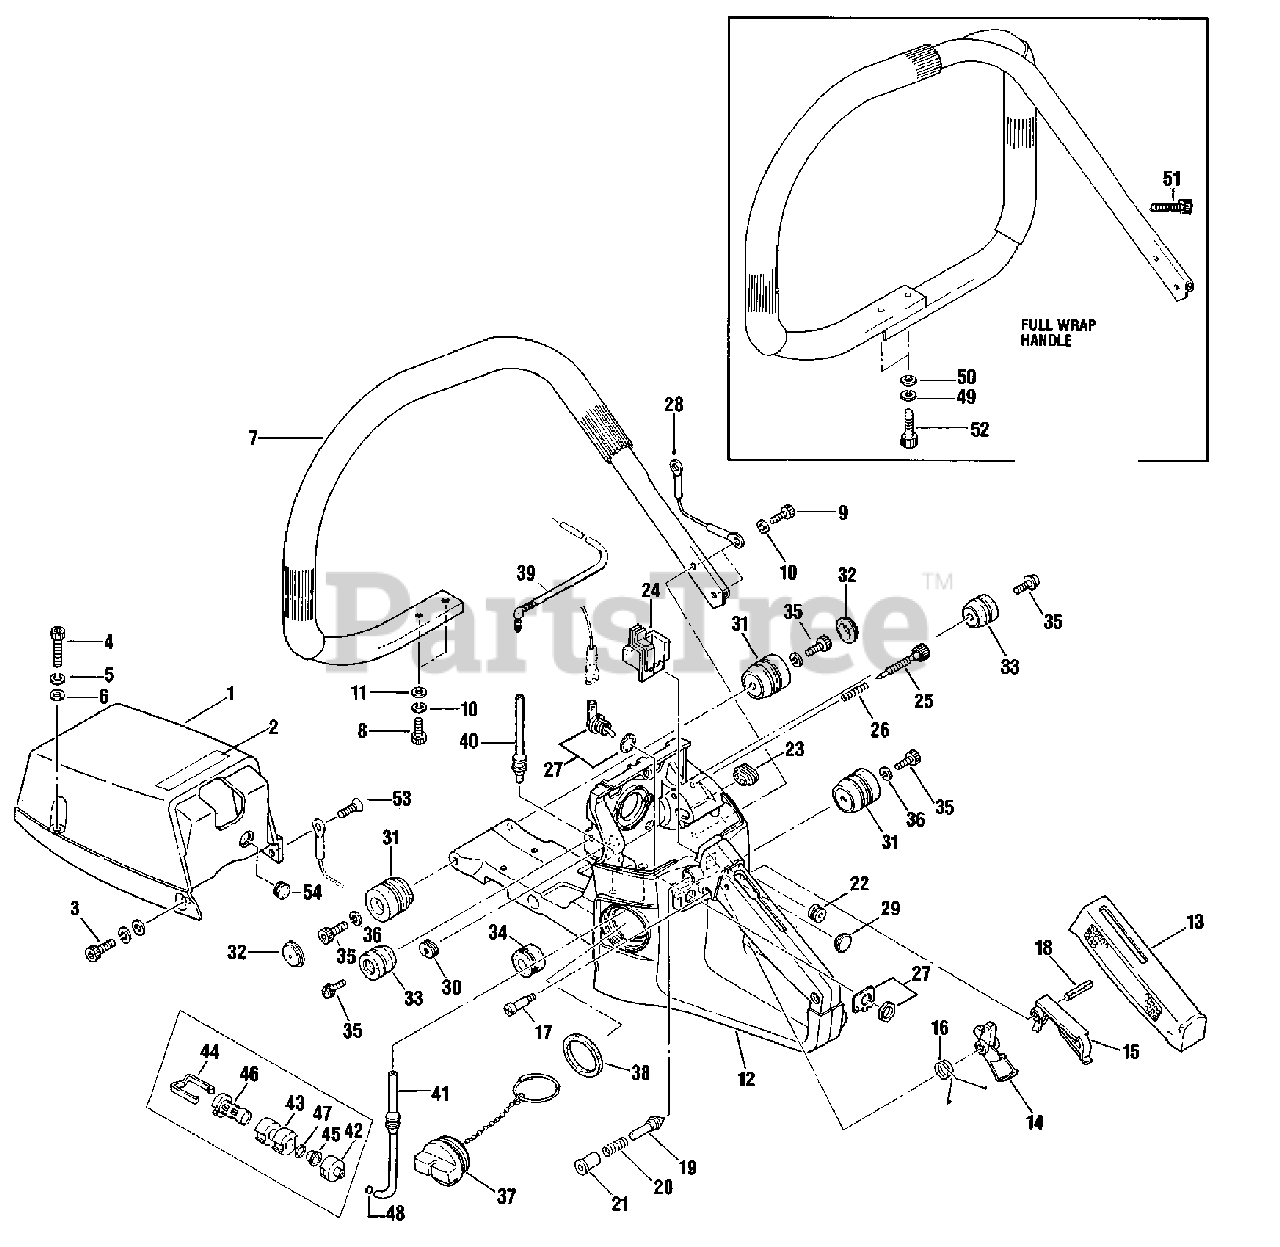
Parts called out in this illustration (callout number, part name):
1	COVER, ENGINE
2	LABEL - CAUTION
3	BOLT
4	BOLT 5×25
5	WASHER, SPRING 5
6	WASHER, FLAT 5.5×10×0.8
7	HANDLE, FRONT
8	BOLT
9	BOLT M5×18
10	WASHER, SPRING 5
11	WASHER, FLAT 5.5×10×0.8
12	REAR HANDLE ASSY
13	GRIP, HANDLE
14	TRIGGER, THROTTLE
15	LEVER, LOCK
16	SPRING, RETURN
17	BOLT, LEVER
18	SPRING PIN
21	KNOB, STOPPER
22	GROMMET, CHOKE
23	GROMMET, CARBURETOR
24	ROD, GROMMET
25	SCREW, ADJUST
26	SPRING, ADJUST
27	SWITCH ASSY
28	LEAD - GROUND
29	PLUG, RUBBER
30	GROMMET
31	CUSHION 26
32	CAP, CUSHION
33	CUSHION 22
34	SUPPORT
35	BOLT, STOPPER LIMITER
36	WASHER, SPRING 5
37	CAP, FUEL
38	GASKET
39	BREATHER ASSY
40	TUBE
41	PIPE
42	WEIGHT, FUEL LINE
43	FILTER, FUEL
44	CLIP, FILTER
45	SCREEN, FILTER
46	BODY, FUEL FILTER
47	RING, RETAINING
48	CLIP Ø6
49	WASHER, SPRING 5
50	WASHER, FLAT 5.5×10×0.8
51	BOLT
52	BOLT 5×30
53	SCREW - 5×12
54	PLUG
